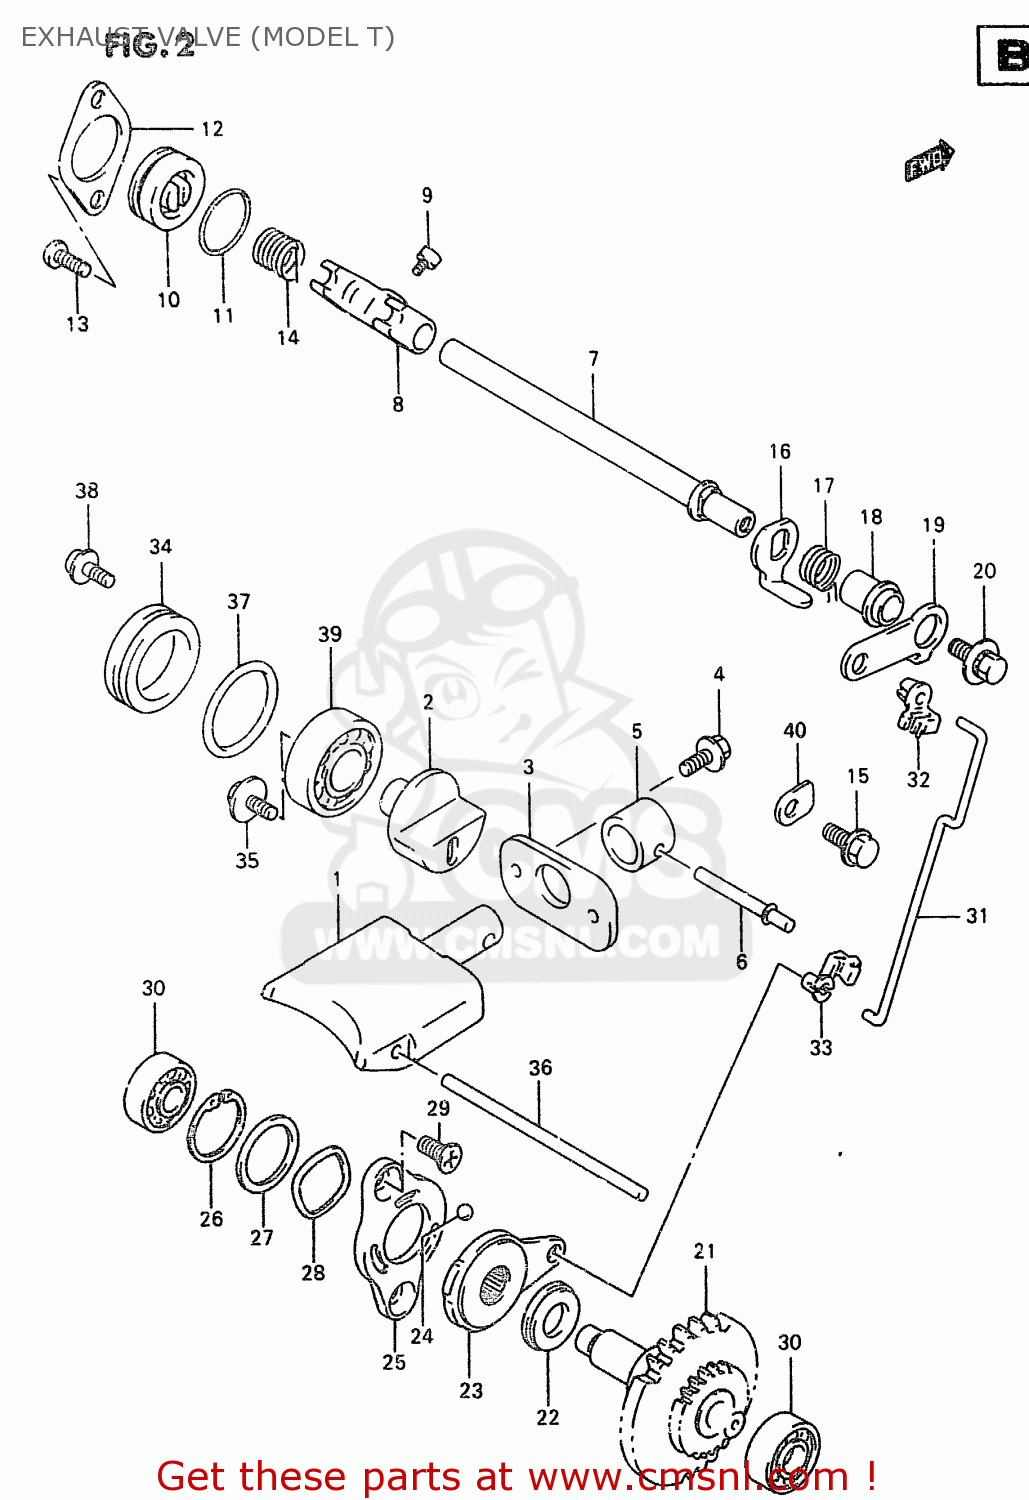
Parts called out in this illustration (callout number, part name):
1	VALVE,EXHAUST MAIN
2	VALVE,EXHAUST SIDE
3	GUIDE,EXHAUST MAIN VALVE
4	SCREW 5X12
5	SPACER,EXHAUST VALVE
6	PIN,EXH MAIN VALVE & SPACER
7	SHAFT,EXHAUST VALVE
8	ARM,EXHAUST VALVE SHAFT
9	BOLT(4X8)
10	CAP,EXHAUST VALVE
11	O RING(D:1.9,ID:22.6)
12	RETAINER,EXHAUST VALVE
13	BOLT
14	SPRING
15	BOLT
16	LEVER,EXHAUST VALVE NO.2
17	SPRING
18	SPACER,EXHAUST VALVE
19	LEVER,EXHAUST VALVE NO.1
20	BOLT(5X12)
21	GOVERNOR ASSEMBLY,EXHAUST VALVE
22	BEARING(10X22X2.8)
23	ACTUATOR,EXHAUST VALVE
24	BALL
25	STARTER,EXHAUST VALVE ACTUATOR
26	CIRCLIP
27	SHIM(19.1X25X0.3)
28	WASHER
29	SCREW(5X10)
30	BEARING(8X22X7)
31	ROD,EXHAUST VALVE
32	BUSH,EXHAUST VALVE ROD NO.1
33	BUSH,EXHAUST VALVE ROD NO.2
34	CAP,EXHAUST SIDE VALVE
35	BOLT(5X12)
36	PIN
37	O RING(D:3.1,ID:26.4)
38	SCREW 5X12
39	BEARING
40	RETAINER
